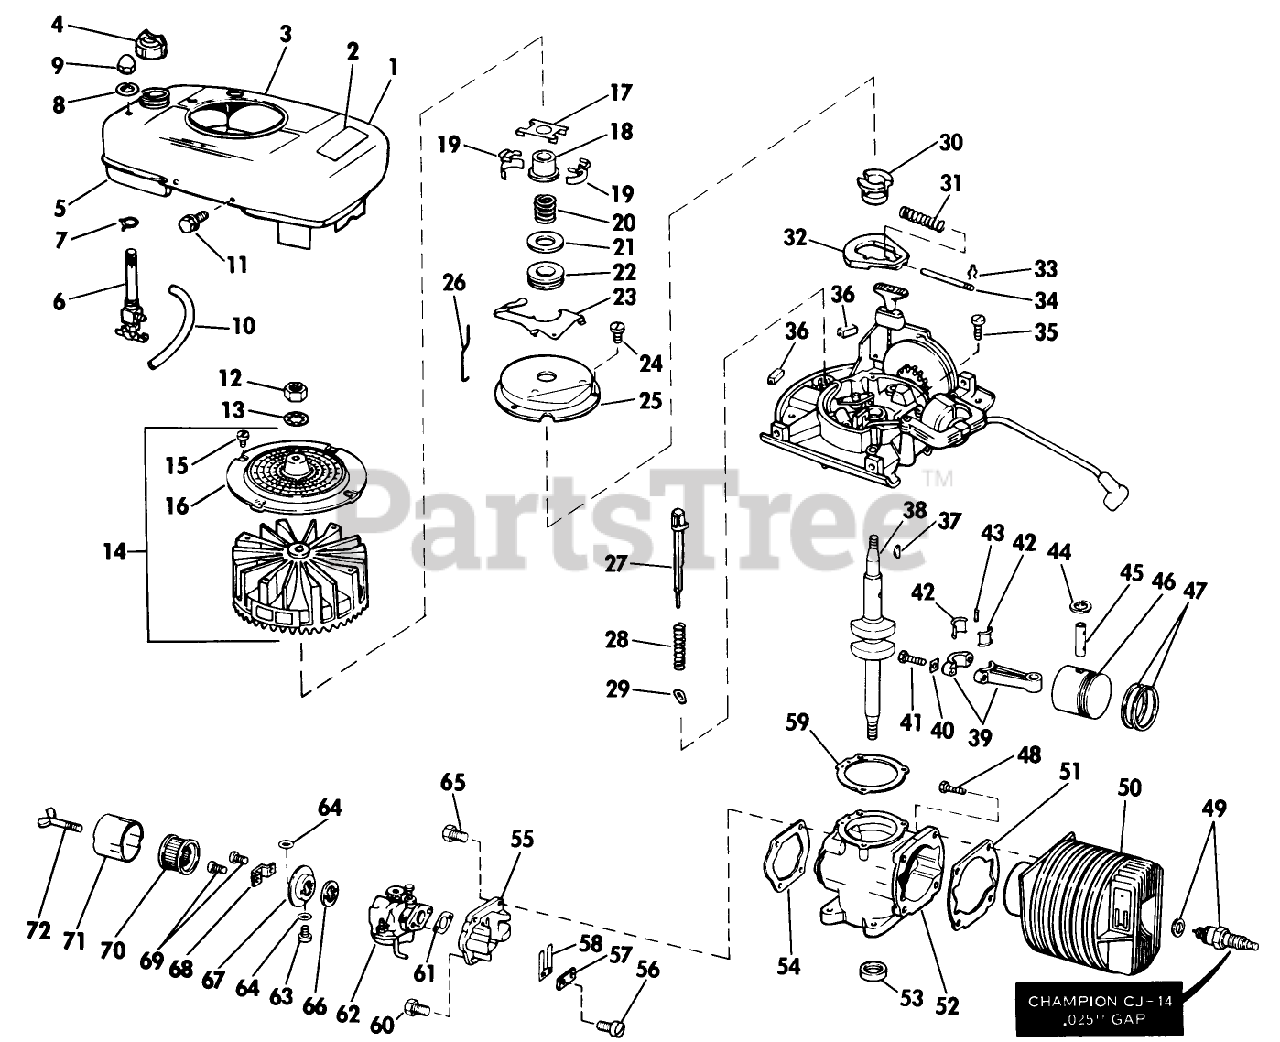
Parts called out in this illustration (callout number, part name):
6	VALVE&SCREEN SM
7	CLAMP - HOSE S
9	PALNUT S
11	SCREW S
14	Flywheel Screen Assy.
15	SCREW F
18	COLLAR S
22	THRUST COLLAR S
23	LEVER-GOVERNOR S
24	SCREW S
25	DUST COVER S
28	SPRING S
30	SPARK ADV. S
31	SPARK ADV. SPRING S
32	FLYWEIGHT S
33	SPARK ADJ. SPRING
34	PIN,SPARK ADV. S
42	LINER ASM
44	RING-RETAINING
49	Spark Plug Gasket (Champion CJ-14, .025" Gap)
51	GASKET S
54	GASKET S
55	REED PLATE AY. S
57	PLATE-BACKUP, REED
59	GASKET S
60	SCREW S
61	GASKET S
65	SCREW S
66	GASKET S
